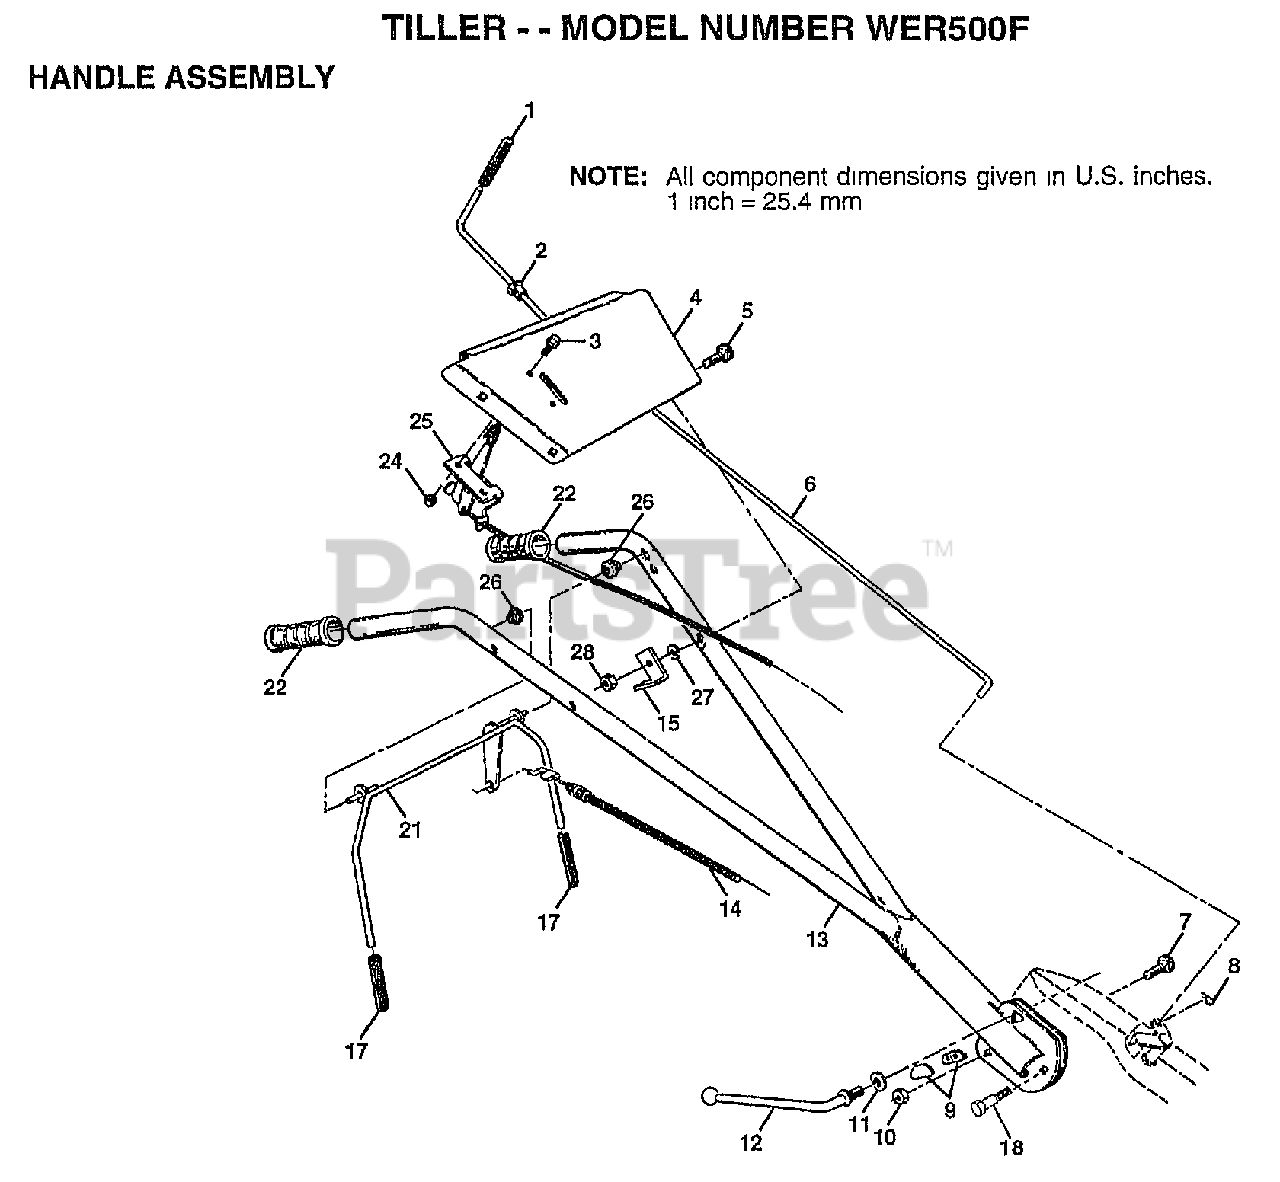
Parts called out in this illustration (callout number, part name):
1	GRIP TI
2	BUSHING
3	SCREW.PNHD.10-24
4	BRACKET.HDLE.TILL
5	BOLT CARRIAGE CRT
6	ROD SHIFT CRT
7	BOLT D
8	RETAINER M
9	LOCK CRT
10	LOCKNUT
11	WASHER CRT
12	LEVER LOCK CRT
13	HANDLE.ASM.V-PLOW
14	CABLE.CLUTCH.Z-BE
15	BRACKET.CLUTCH.CA
17	GRIP BAR CRT
18	BOLT PIVOT
21	BAR.ASM.CNTRL.VPL
22	"GRIP,HANDLE"
23	NUT
25	"CONT,THROTTLE"
26	GROMMET.HANDLE.V-
27	LOCKWASHER
